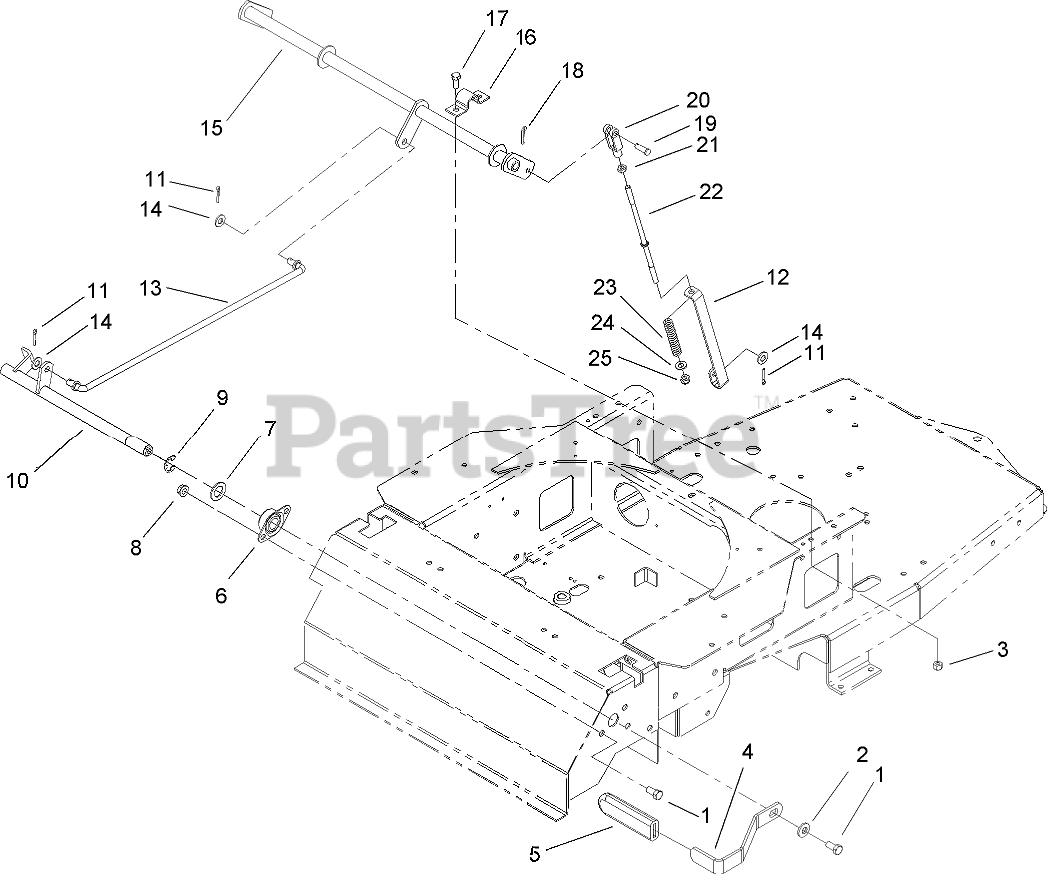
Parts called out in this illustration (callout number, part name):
1	SCREW-HH
2	WASHER-BELLEVILLE
3	NUT-LOCK, NI
4	HANDLE-BRAKE, PARK
5	GRIP-LEVER
6	BEARING-FLANGE, SIDE
7	WASHER
8	NUT-HHF, WHIZ
9	E-RING
10	BRAKE SHAFT ASM
11	PIN-COTTER
12	BRACKET-SPRING, BRAKE
13	ROD-BRAKE, UPPER
14	WASHER-FLAT
15	SHAFT-BRAKE
16	CLAMP-PIVOT, HOC
17	SCREW-HH
18	PIN-COTTER
19	PIN-CLEVIS
20	YOKE-ADJUSTABLE
21	NUT-HEX
22	ROD-BRAKE, UPPER
23	SPRING
24	WASHER-PLAIN
25	NUT-LOCK
